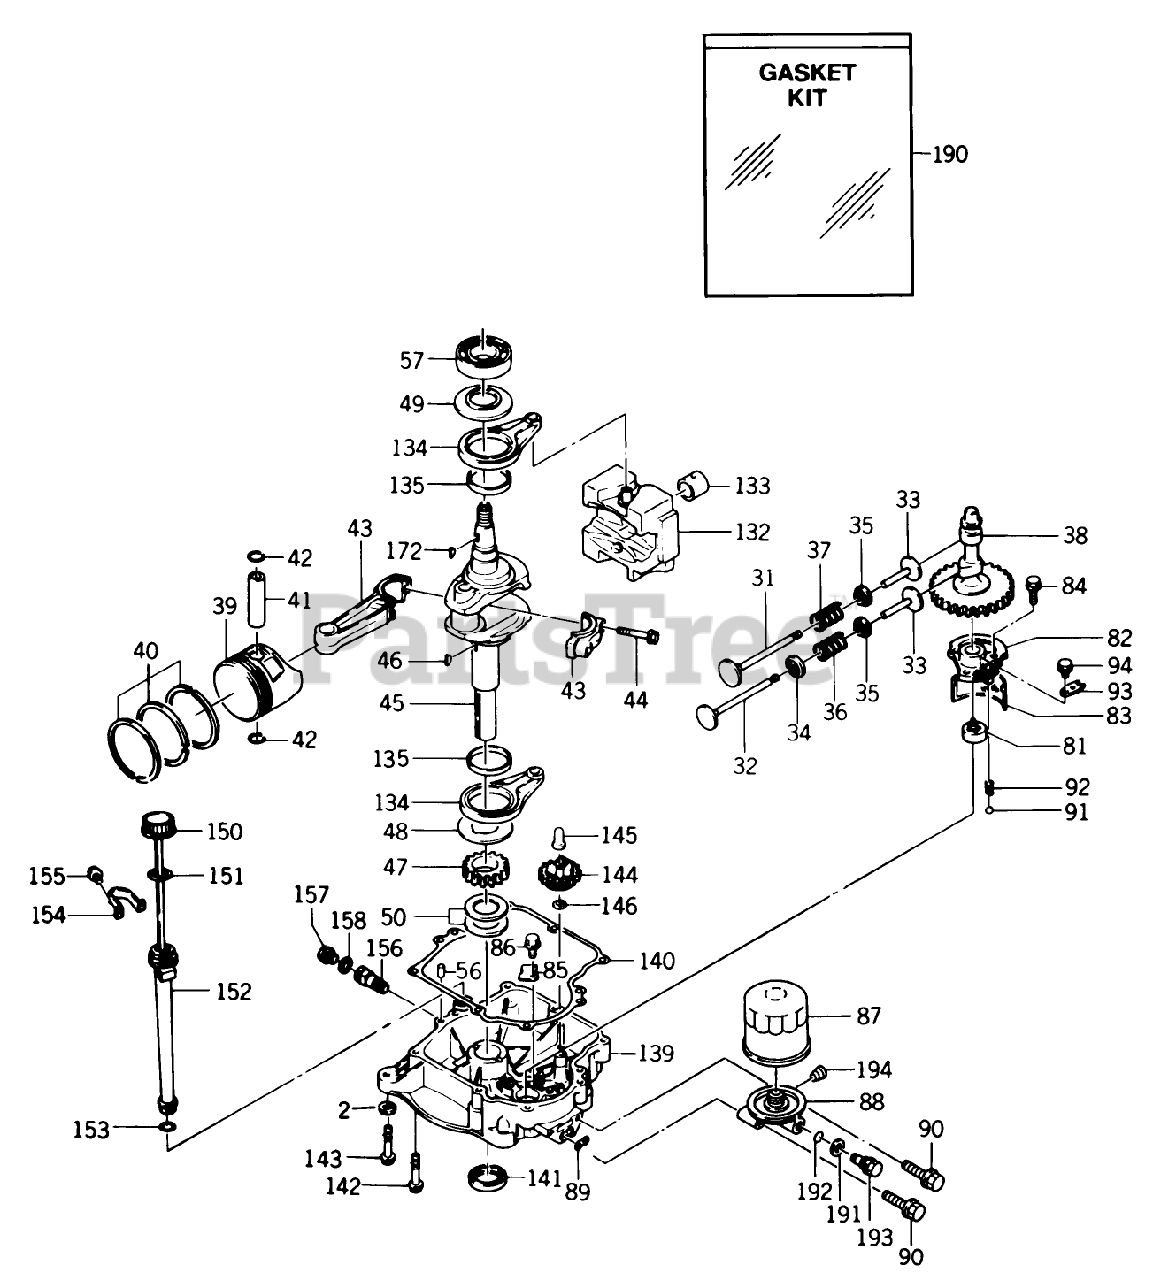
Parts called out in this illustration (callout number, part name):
2	920008 Washer 5/16 SAE
32	VALVE-EXHAUST
45	CRANKSHAFT
46	KEY-WOODRUFF
88	11044-2065 Bracket (includes item 194)
90	BOLT-FLANGED
94	BOLT-FLANGED
139	COVER-CRANKCASE
140	GASKET
142	BOLT-FLANGED
144	GOVERNON
145	SLEEVE-GOVERNOR
150	GAUGE-OIL
151	GASKET
153	O-RING
157	PLUG DRAIN
158	GASKET
172	KEY-WOODRUFF
191	11009-2175 Gasket
